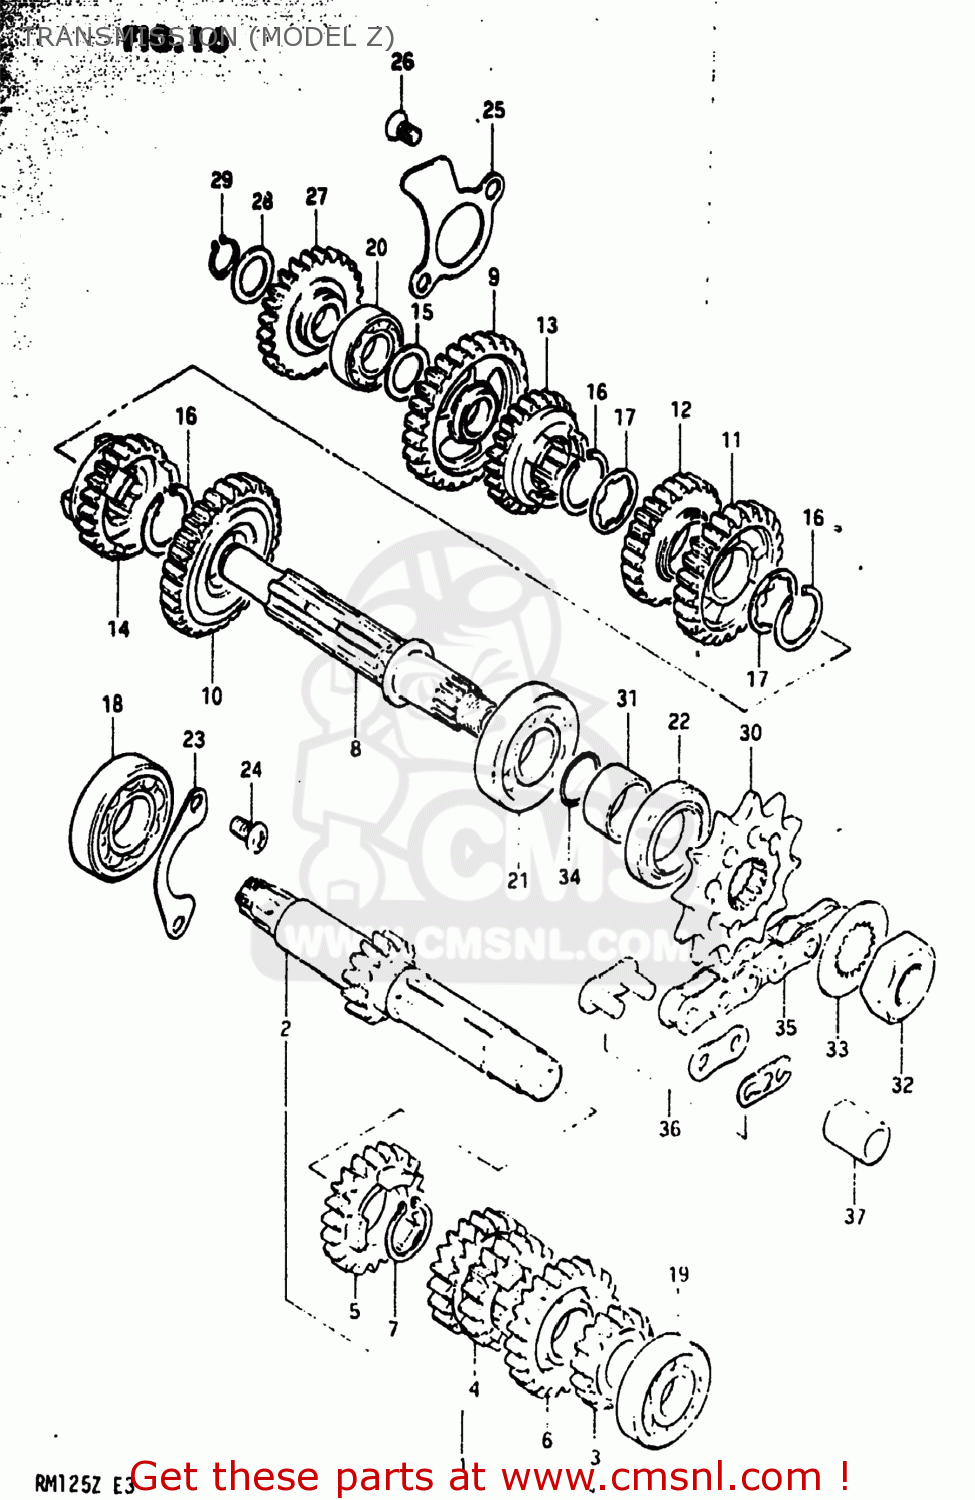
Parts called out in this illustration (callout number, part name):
1	SHAFT,COUNTER
2	SHAFT,COUNTER
3	GEAR,SECOND DRIVE
4	GEAR,THIRD/FOURTH DRIVE
5	GEAR,FIFTH DRIVE
6	GEAR,SIXTH DRIVE
7	CIRCLIP
8	SHAFT,DRIVE
9	GEAR,FIRST DRIVEN
10	GEAR,SECOND DRIVEN
11	GEAR,THIRD DRIVEN
12	GEAR,FOURTH DRIVEN
13	GEAR,FIFTH DRIVEN
14	GEAR,6TH DRIVEN
15	WASHER,THRUST
16	CIRCLIP
17	WASHER,LOCK
18	Bearing
19	BEARING
20	BEARING, RH
21	BEARING(20X47X14)
22	SEAL,OIL(25X40X7)
23	RETAINER,CNTR SHAFT BEARING
24	SCREW 6X12
25	RETAINER,DRIVESHAFT
26	SCREW
27	GEAR,KICK STARTER IDLE
28	WASHER,THRUST
29	CIRCLIP,15MM
30	SPROCKET,ENGINE
31	SPACER(20X25X12.5)
32	NUT
33	WASHER,LOCK
34	O RING(D:1,ID:19.5)
35	CHAIN ASSEMBLY,DRIVE
36	JOINT ASSEMBLY,CHAIN
37	CUSHION
